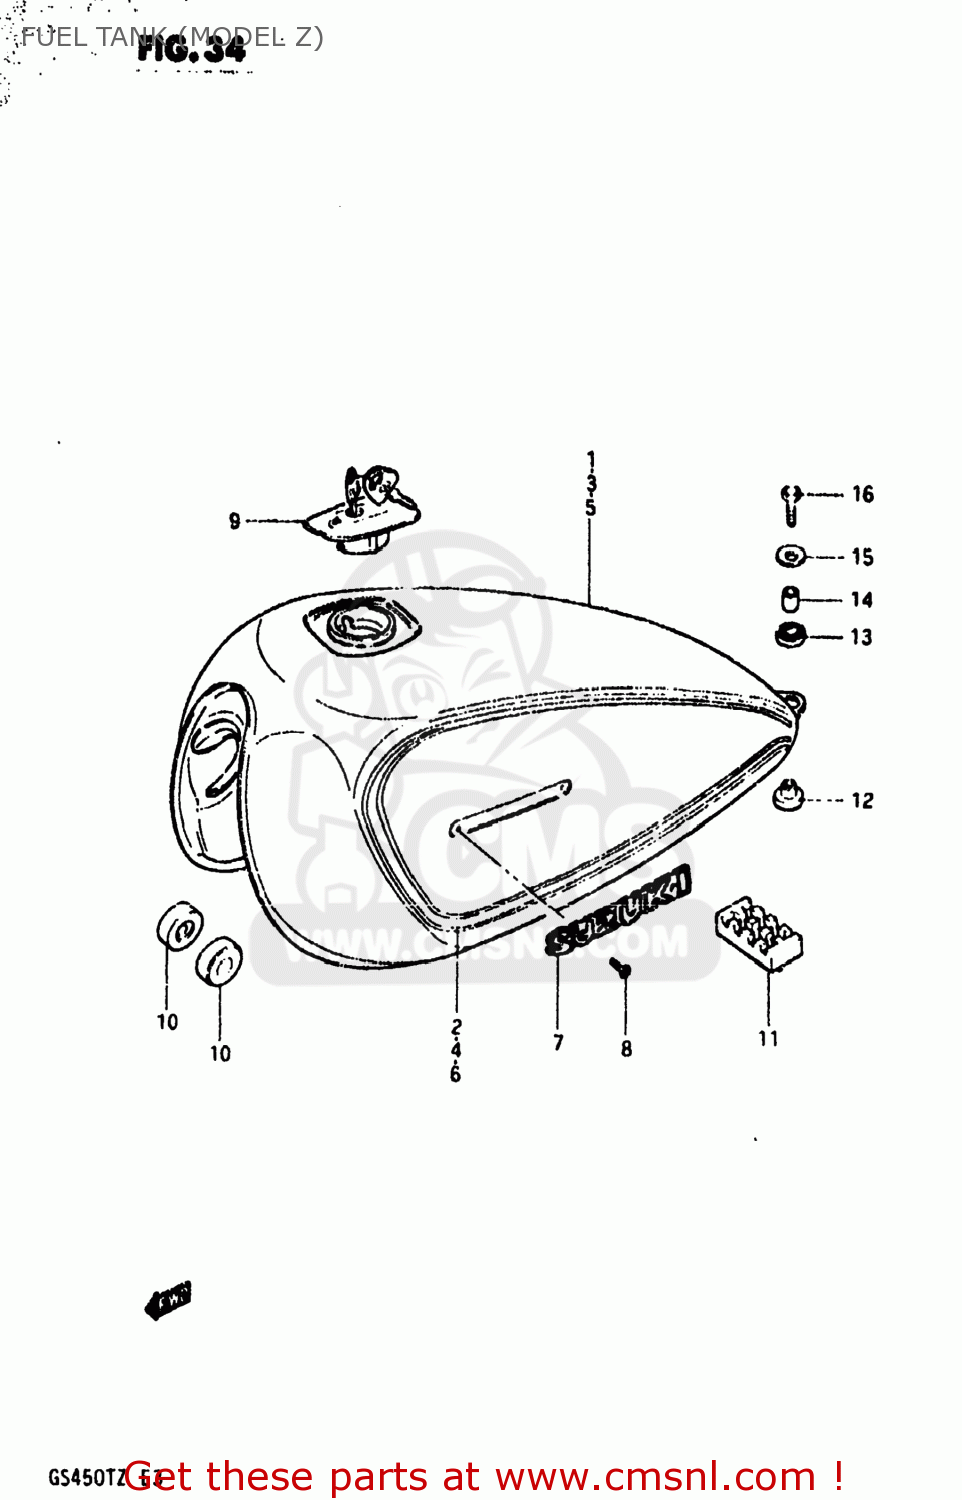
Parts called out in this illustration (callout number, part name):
1	TANK ASSEMBLY,FUEL
2	TAPE SET,FUEL TANK
3	TANK ASSEMBLY,FUEL
4	TAPE SET,FUEL TANK
5	TANK ASSEMBLY,FUEL
6	TAPE SET,FUEL TANK
7	EMBLEM,FUEL TANK
8	SCREW 3X6
9	CAP SET,FUEL TANK
10	CUSHION
11	CUSHION,FUEL TANK CTR
12	CUSHION
13	CUSHION
14	SPACER
15	WASHER (6.5X24X1.6)
16	BOLT 6X27
